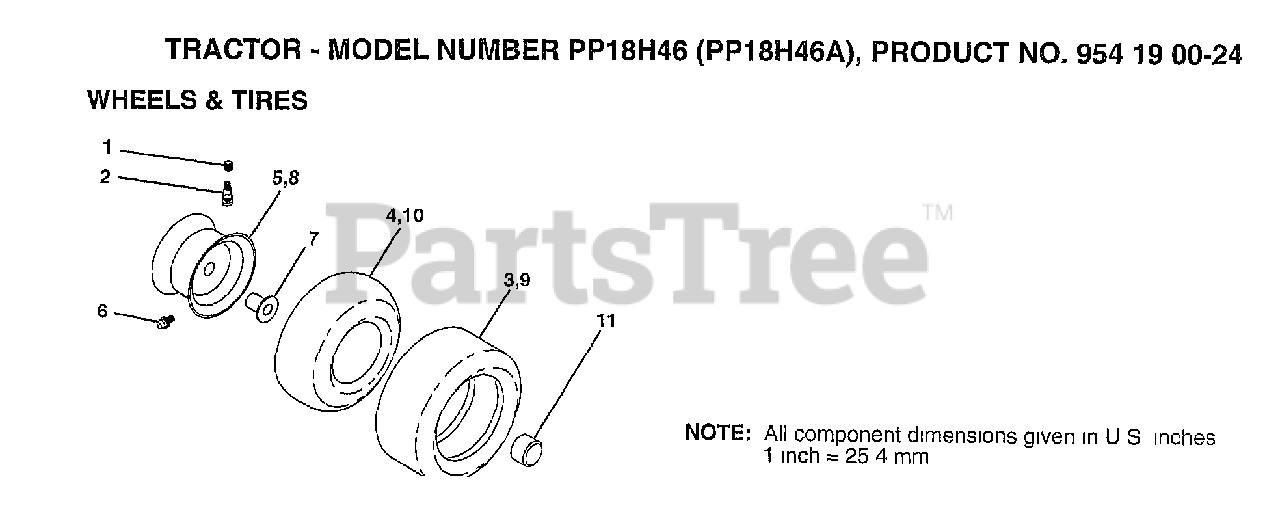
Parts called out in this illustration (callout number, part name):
1	VALVE CAP
2	VALVE STEM LT
4	TUBE.5.3/4.5/6
5	"RIM,FRT T"
6	FITTING LT
7	"FLANGE, BEARING"
8	"RIM 8"""
10	TUBE.18X9.5-8
11	HUB CAP
